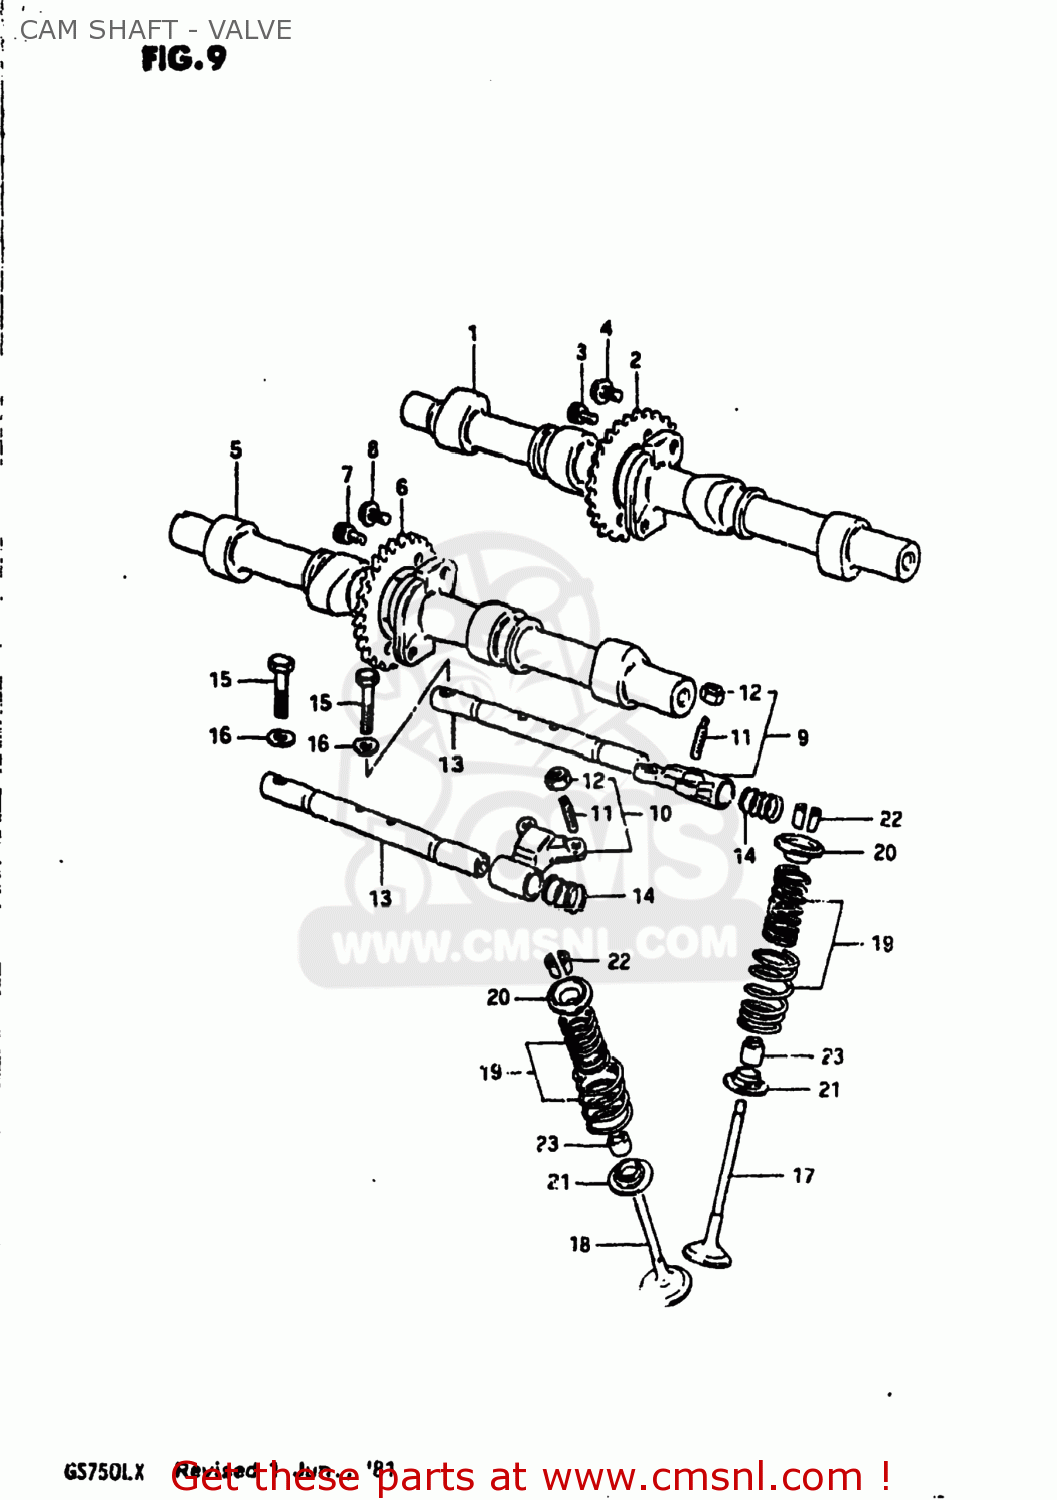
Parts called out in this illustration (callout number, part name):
1	CAMSHAFT
2	SPROCKET,CAMSHAFT
3	BOLT 6X11
4	BOLT(7X11)
5	CAMSHAFT,EXHAUST
6	SPROCKET,EXHAUST CAMSHAFT
7	BOLT 6X11
8	BOLT(7X11)
9	ARM,VALVE ROCKER
10	ARM,VALVE ROCKER
11	SCREW,TAPPET ADJUSTING
12	NUT,ADJUSTING
13	SHAFT,VALVE ROCKER
14	SPRING
15	BOLT
16	WASHER
17	VALVE,INTAKE
18	VALVE,EXHAUST
19	SHIM,TAPPET
20	RETAINER,VALVE SPRING
21	SEAT,VALVE SPRING
22	COTTER VALVE
23	OIL SEAL
